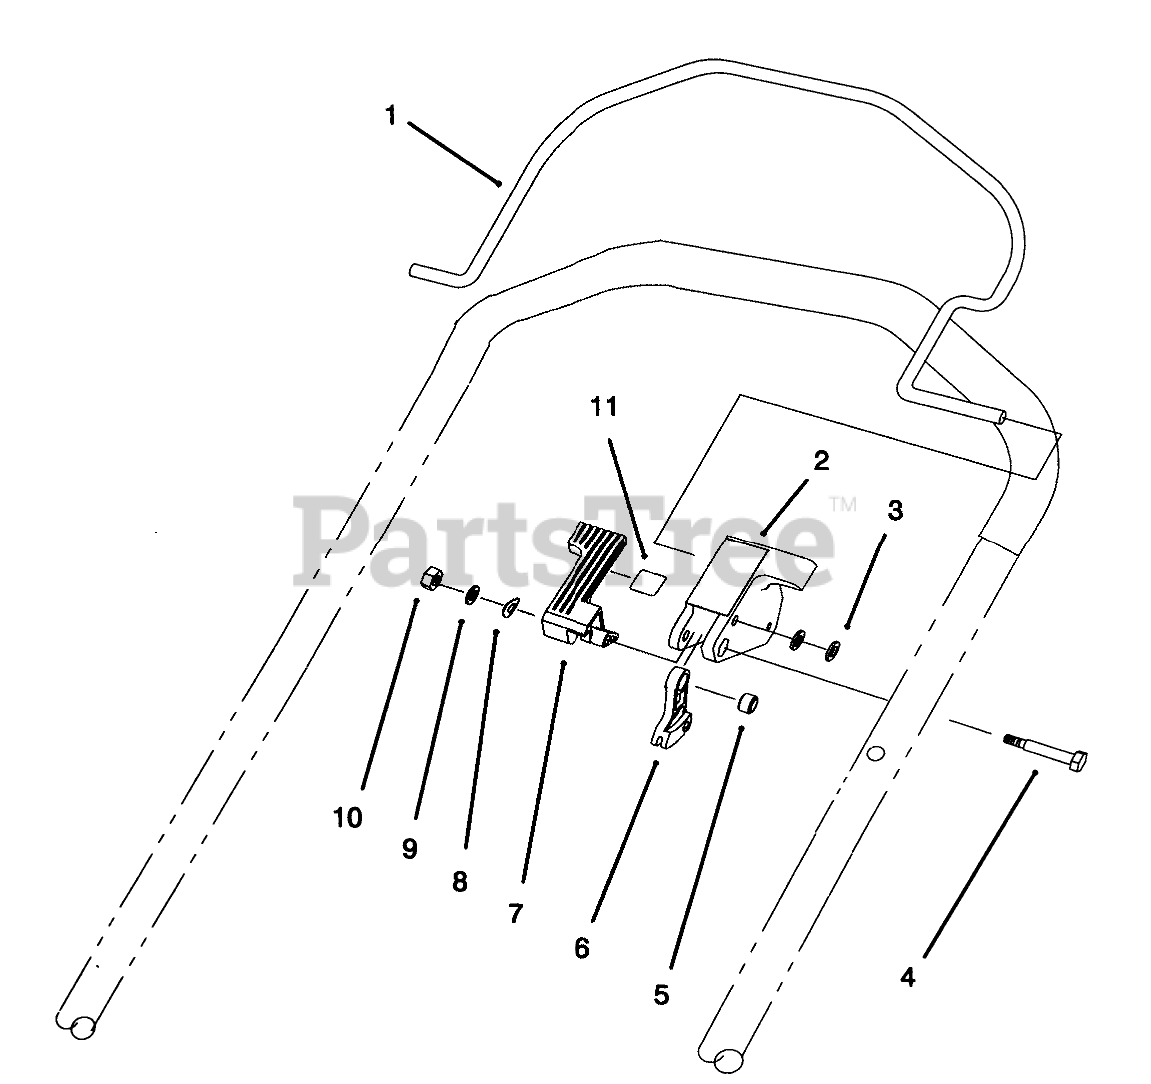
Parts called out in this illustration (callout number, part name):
1	BAIL - CONTROL
2	STOP - PIVOT, PLASTIC
3	WASHER-FLAT
4	SHOULDER BOLT
5	SPACER-LEVER, TRACTION
6	LEVER-TRACTION
7	LEVER - SHIFT
8	WASHER - SPRING
9	WASHER-PLAIN
10	NUT-LOCK, NI
11	DECAL - TRACTION
